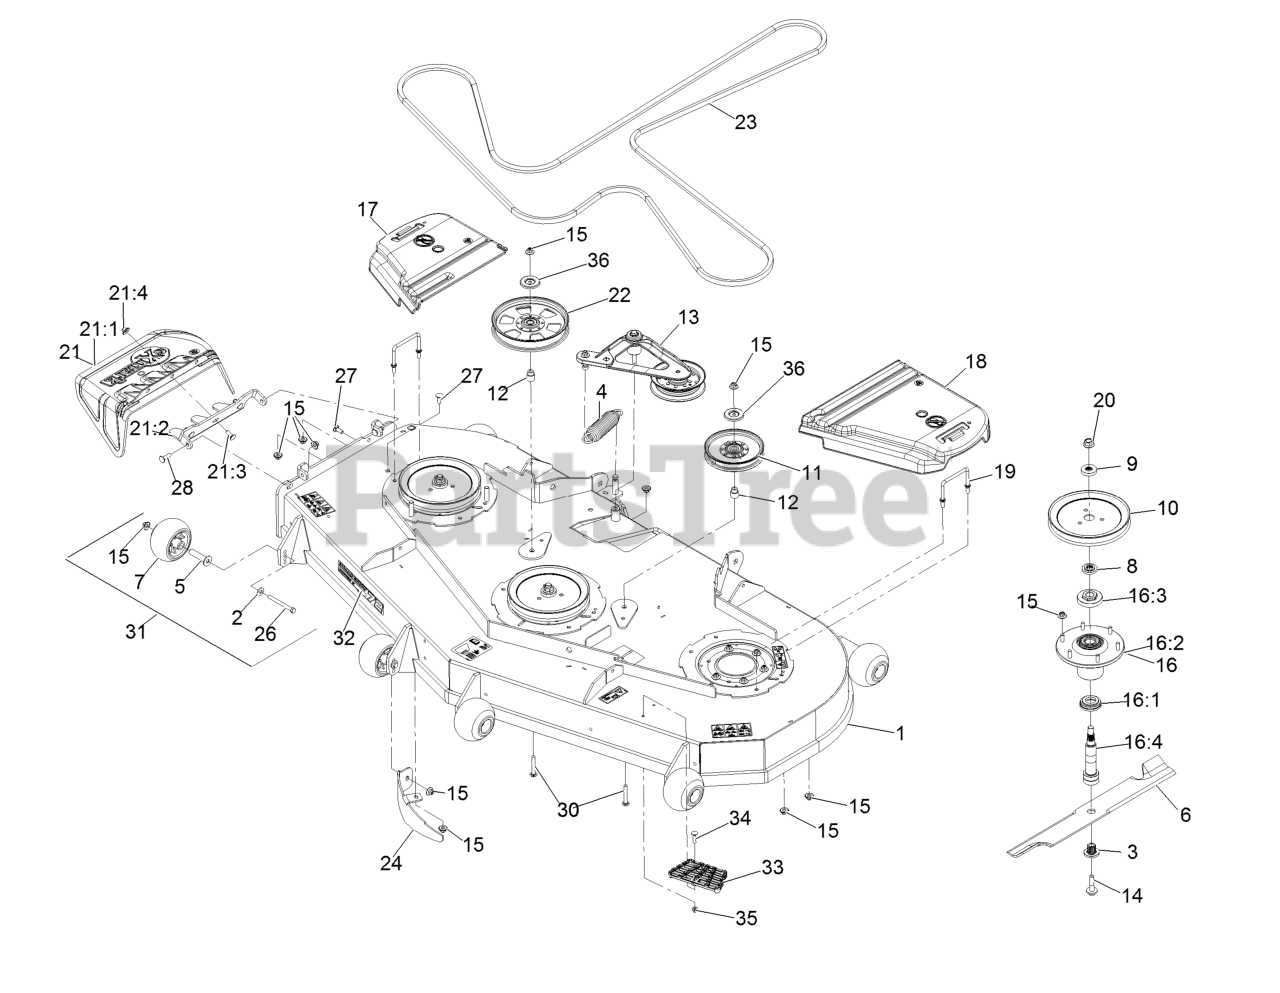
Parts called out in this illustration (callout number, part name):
1	ASM,Deck W/Decals 724
2	Washer-Belleville
3	Bushing, Splined
4	Spring-Extension
5	Axle, Roller
6	Blade, Solid (72")
6	Blade, Low Lift (72")
6	Blade, Mulching
6	Blade, Notched (72")
6	Blade-Extreme 2, 24.50"
7	Roller-Anti-Scalp
8	Spacer, Splined Stepped
9	Spacer, Splined
10	Sheave,Blade Drive 9.00
11	Idler-Pulley
12	Bushing, Idler
13	Deck Idler ASM
14	Screw-Sems 1/2-20 X 2.19
15	Nut-Nyloc 3/8-16 Flg
16	ASM,Spindle Housing
16:1	Guard, Bottom
16:2	Asm, Cutter Housing
16:3	Nut, Spindle 7/8-14
16:4	Spindle,Double Spline
17	Cover-Belt, RH
18	Cover-Belt, LH
19	Wireform-Cover
20	Nut-Flange 5/8-18 Centerlock
21	ASM,Discharge Chute
21:1	Chute, Discharge
21:2	Bracket,Discharge Chute
21:3	Bolt-Carriage 3/8-16 X 1
21:4	Nut-Nyloc 3/8-16 Flg
22	Pulley-Idler, Flat
23	Belt-V
24	Baffle-Dogleg, Lz72
26	Screw-HH
27	Bolt-Carriage 3/8-16 X 1
28	Bolt-Carriage 3/8-16 X 1 1/4
30	Screw-CARR
31	Kit, Anti-Scalp Roller
32	Decal, 726
33	Step-Deck
34	Bolt-Carriage 5/16-18 X 1 1/4
35	Nut-Nyloc 5/16-18 Flg
36	Shield-Dust
